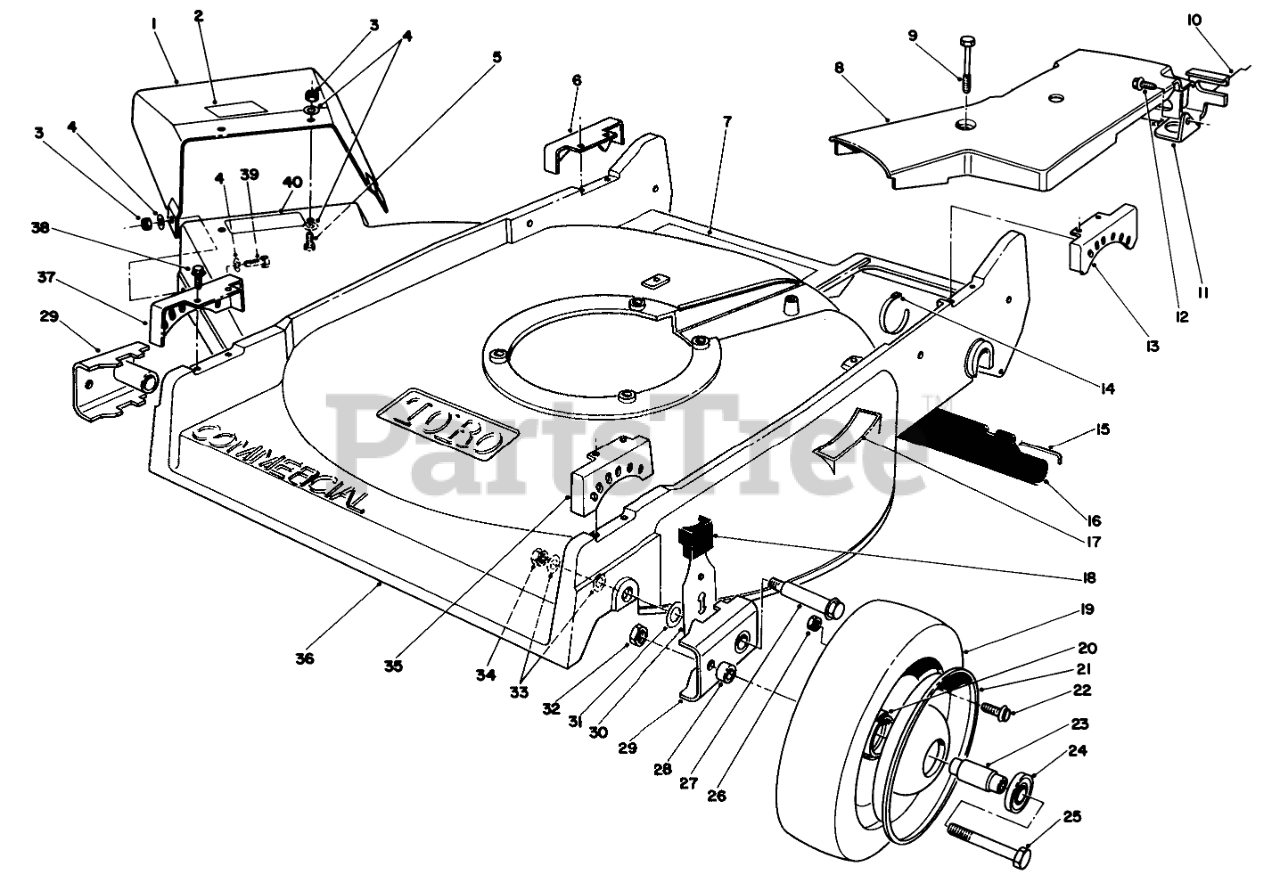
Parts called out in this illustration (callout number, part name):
1	Deflector Assy. (Incl. Ref. #2)
2	Decal Danger
3	NUT-LOCK, NI
4	WASHER-FLAT
5	SCREW-HH
6	QUADRANT-REAR, RH
7	Decal-Safety Instructions
8	Decal-Hot
9	SCREW-HHFTF
10	RETAINER-CABLE
11	Bracket-Traction Adj.
12	SCREW-HWHTF
13	QUADRANT-REAR, LH
14	TIE-CABLE
15	ROD-SHIELD
16	SHIELD-TRAILING
17	DECAL - STEP PAD INT'L
18	KNOB-ARM
20	HUB-BEARING
21	Wheel-Half
22	SCREW-HHF
23	SPACER-BEARING
24	BEARING-WHEEL
25	SCREW-HH
26	NUT-LOCK, NI
27	WHEEL BOLT
28	SPACER-WHEEL
29	ARM-PIVOT, FRONT
30	FRONT SPRING ARM ASM
31	WASHER-THRUST
32	NUT-LOCK, CONE
33	WASHER
34	Nut
35	QUADRANT-FRONT, LH
36	Housing-Commercial (Inc. Ref. #7, 17, & 40)
37	QUADRANT-FRONT, RH
38	SCREW-HWHTF
39	SCREW-HH
40	DECAL - WARNING/INT'L
